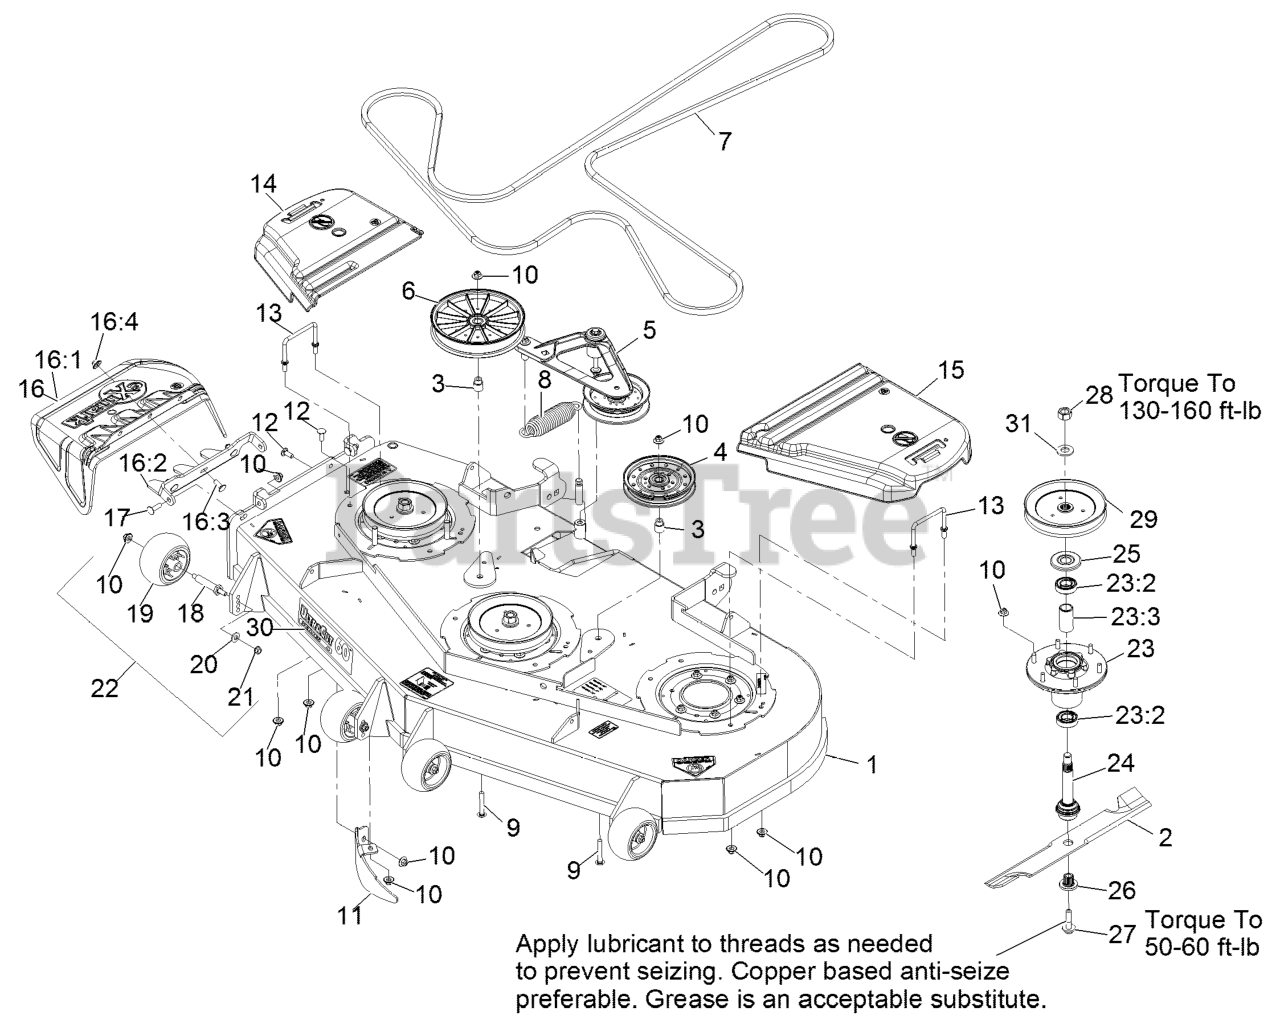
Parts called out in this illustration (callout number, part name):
1	DECK ASM,W/DECALS 60
2	Blade-Extreme 2, 20.50"
3	BUSHING-IDLER
5	DECK IDLER ASM
6	PULLEY,IDLER 8"FLAT
7	BELT,V-5V-198.75
8	SPRING-EXTENSION
9	SCREW-CARR
10	Nut-Nyloc 3/8-16 Flg
11	DOGLEG - LZ60
12	SCREW-CARR
13	WIREFORM-COVER
14	COVER-BELT, RH
15	COVER-BELT, LH
16	ASM,DISCHARGE CHUTE
16:1	CHUTE,DISCHARGE
16:2	BRACKET,DISCHARGE CHUTE
16:3	SCREW-CARR
16:4	Nut-Nyloc 3/8-16 Flg
17	Bolt-Carriage 3/8-16 X 1 1/4
19	ROLLER-SCALP, ANTI
20	WASHER-BELLEVILLE
21	NUT-HHF, WHIZ
23	ASM-CUTTER HSG WITH BEARINGS
23:2	BEARING-BALL
23:3	SPACER-BEARING
24	ASM-SPINDLE AND SEAL
25	GUARD,BEARING TOP .989
26	BUSHING,SPLINED
27	SCREW,SEMS 1/2-20 X 2.19
28	NUT-HEX
29	SHEAVE,BLADE DRIVE 7.25
30	DECAL,ULTRACUT 60 SERIES
